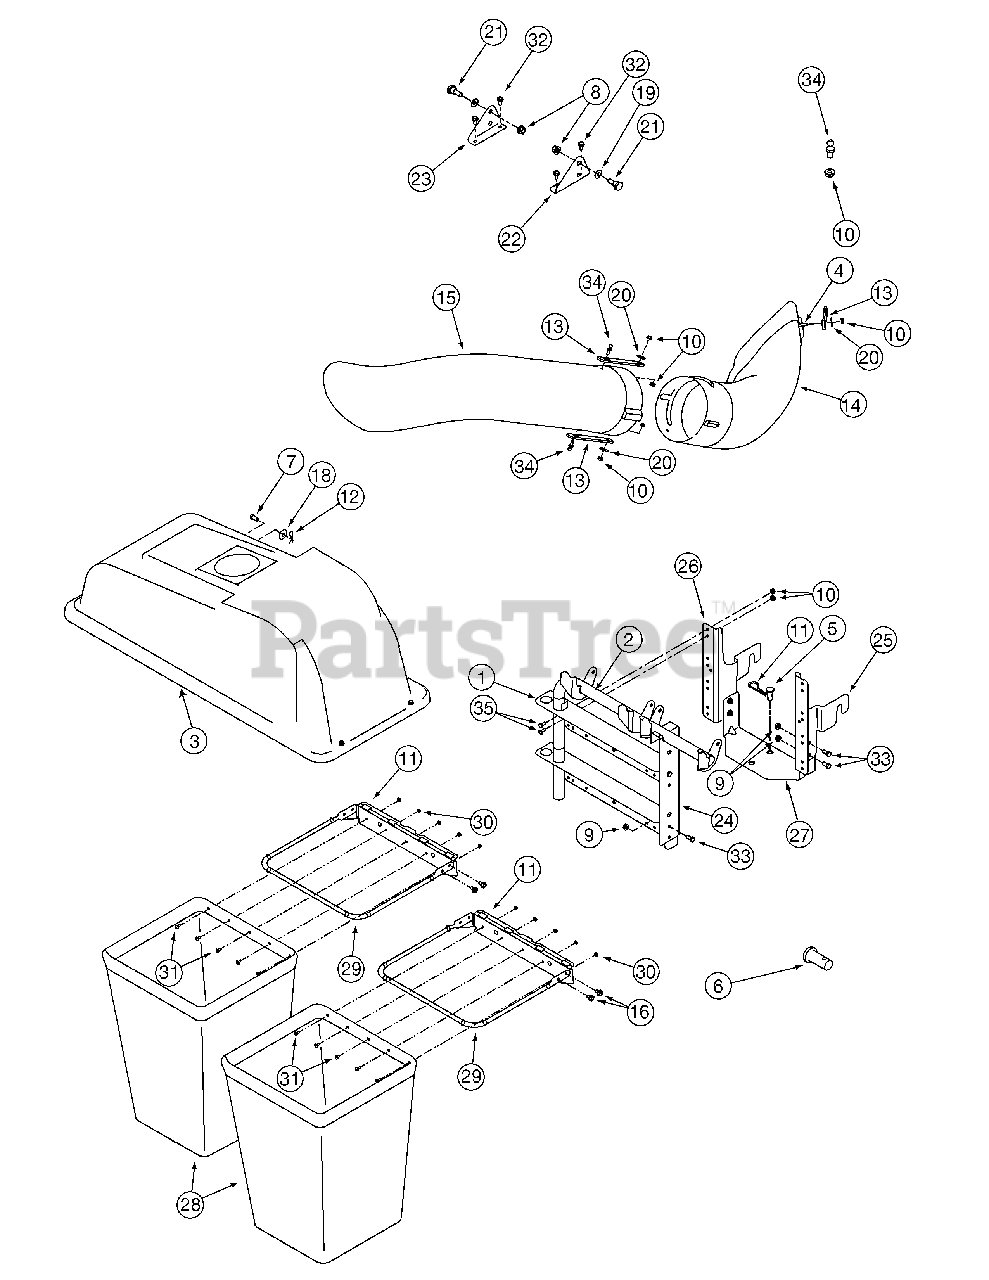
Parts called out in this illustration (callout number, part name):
3	Grass catcher Cover Assembly
4	Screw 1/4-20 x 1"
5	Clevis Pin
6	Clevis Pin (on older model tractors)
7	Clevis Pin
8	Lock Nut 7/16-20
9	Lock Nut 5/16-18
10	Hex Flange Lock Nut, 1/4-20
11	Hairpin Clip
12	Click Pin
13	Chute Strap
14	Discharge Chute 38"/42" Bag
15	Chute Tube
16	Self-Tapping Screw 5/16-18
18	Bell Washer
19	Bell Washer
20	Flat Washer
21	Shoulder Screw
22	Supt. Bracket RH
23	Supt. Bracket LH
28	Catcher Bag
30	Hex Sems Nut, #10-24
31	Machine Screw, , #10-24 x .5
32	AB Screw 5/16-12
33	Hex Head Screw 5/16-18 x .75
34	Grass Catcher Pin 1/4-20
35	Hex Head Screw 1/4-20 x .62
